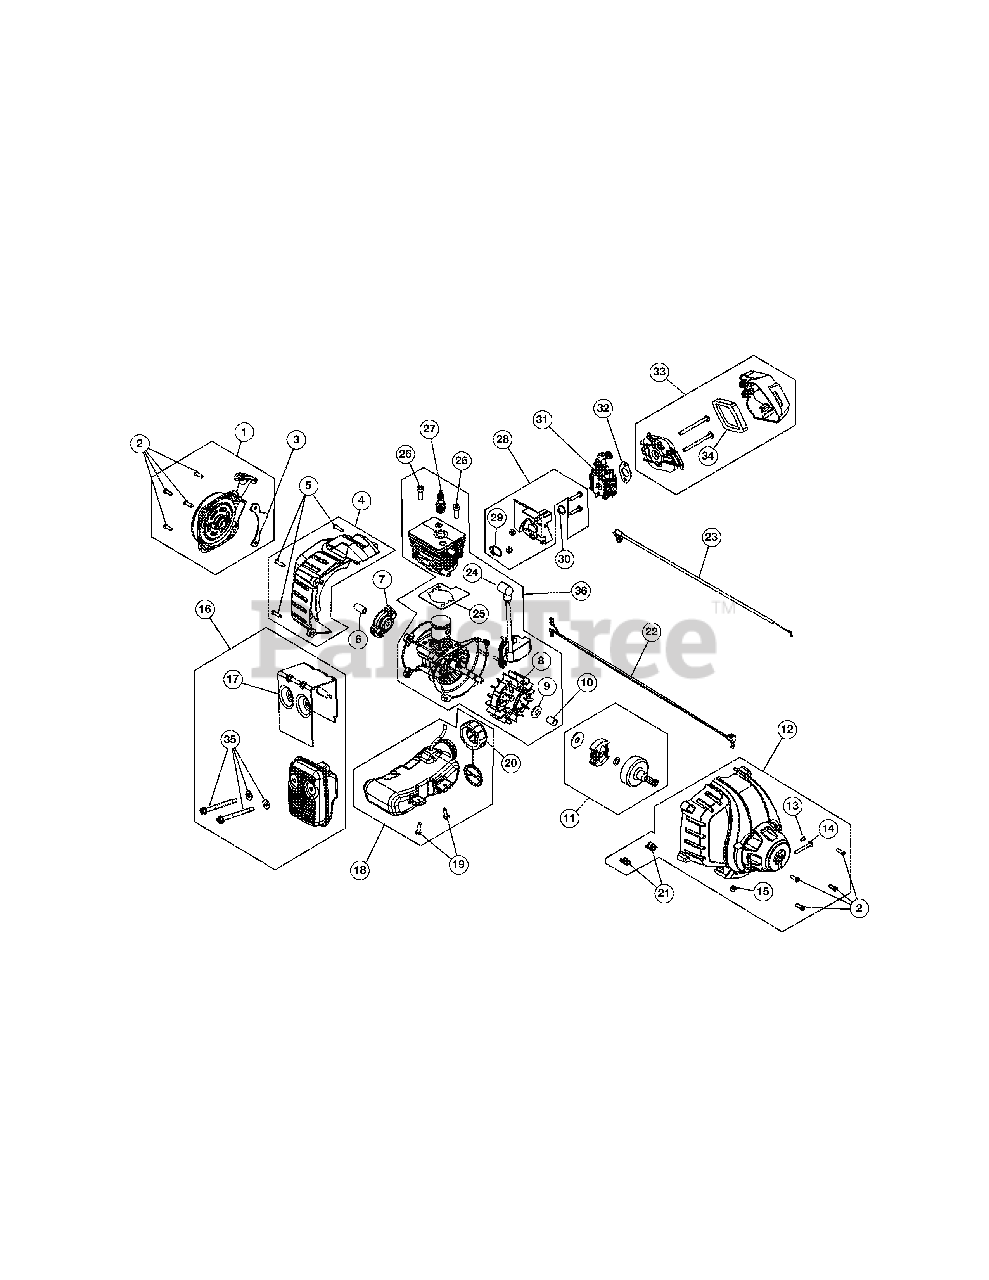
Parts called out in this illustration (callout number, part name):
1	Rear Cover Assembly (Incl Ref No. 2 & 3)
2	Starter Screw
3	Starter Assembly Guard (Incl Ref No. 2)
4	Rear Engine Cover (Incl Ref No. 5)
5	Cover Screw
6	Adapter
7	Pawl Assembly
8	Flywheel Assembly
9	Washer
10	Spacer
11	Clutch Assembly
12	Clutch Cover Assembly (Incl Ref No. 2, 13-15 & 21)
13	Anti-Rotation Screw
14	Clamp Screw
15	Clamp Nut
16	Muffler Assembly (Incl Ref No. 17 & 35)
17	Muffler Gasket
18	Fuel Tank Assembly (Incl Ref No. 19 & 20)
19	Tank Screw
20	Fuel Cap
21	U-Shaped Nut
22	Lead Wires
23	Throttle Cable
24	Module Assembly
25	Cylinder Gasket
26	Cylinder Bolt
27	Spark Plug
28	Insulator Assembly (Incl Ref No. 29 & 30)
29	Insulator O-Ring
30	Carburetor O-Ring
31	Carburetor
32	Carburetor Gasket
33	Aircleaner Assembly (Incl Ref No. 34)
34	Aircleaner Filter
35	Muffler Screw
36	Short Block Assembly
